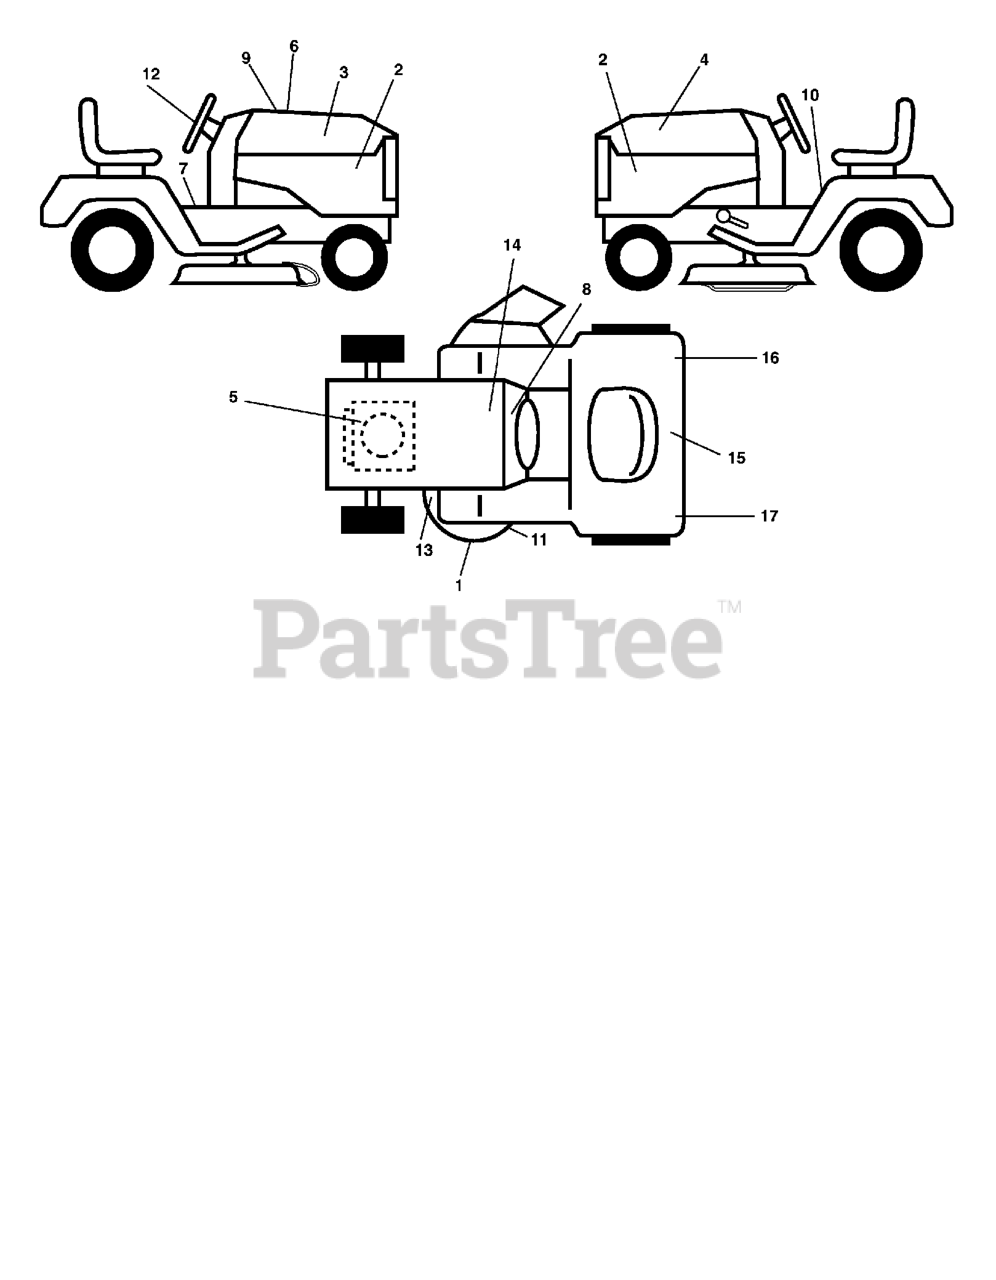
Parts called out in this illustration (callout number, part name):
1	DECAL, MOWER HEAVY DUTY
2	DECAL, PANEL YTH2448
3	DECAL, HOOD RH
4	DECAL, HOOD LH
5	DECAL.ENG.BS.24HP
6	DECAL HOOD CUST. RESP.
7	DECAL.FENDER.HYDRO.ENG
8	DECAL
9	DECAL
10	DECAL
11	DECAL V-BELT SCHEMATIC
12	DECAL.STEERING.HUSQ.BLUE
13	DECAL.MOWER
14	DECAL BTRY SYMBOLS
15	DECAL.FENDER
16	DECAL RH REFLECTOR
17	DECAL REFLECTOR LH
